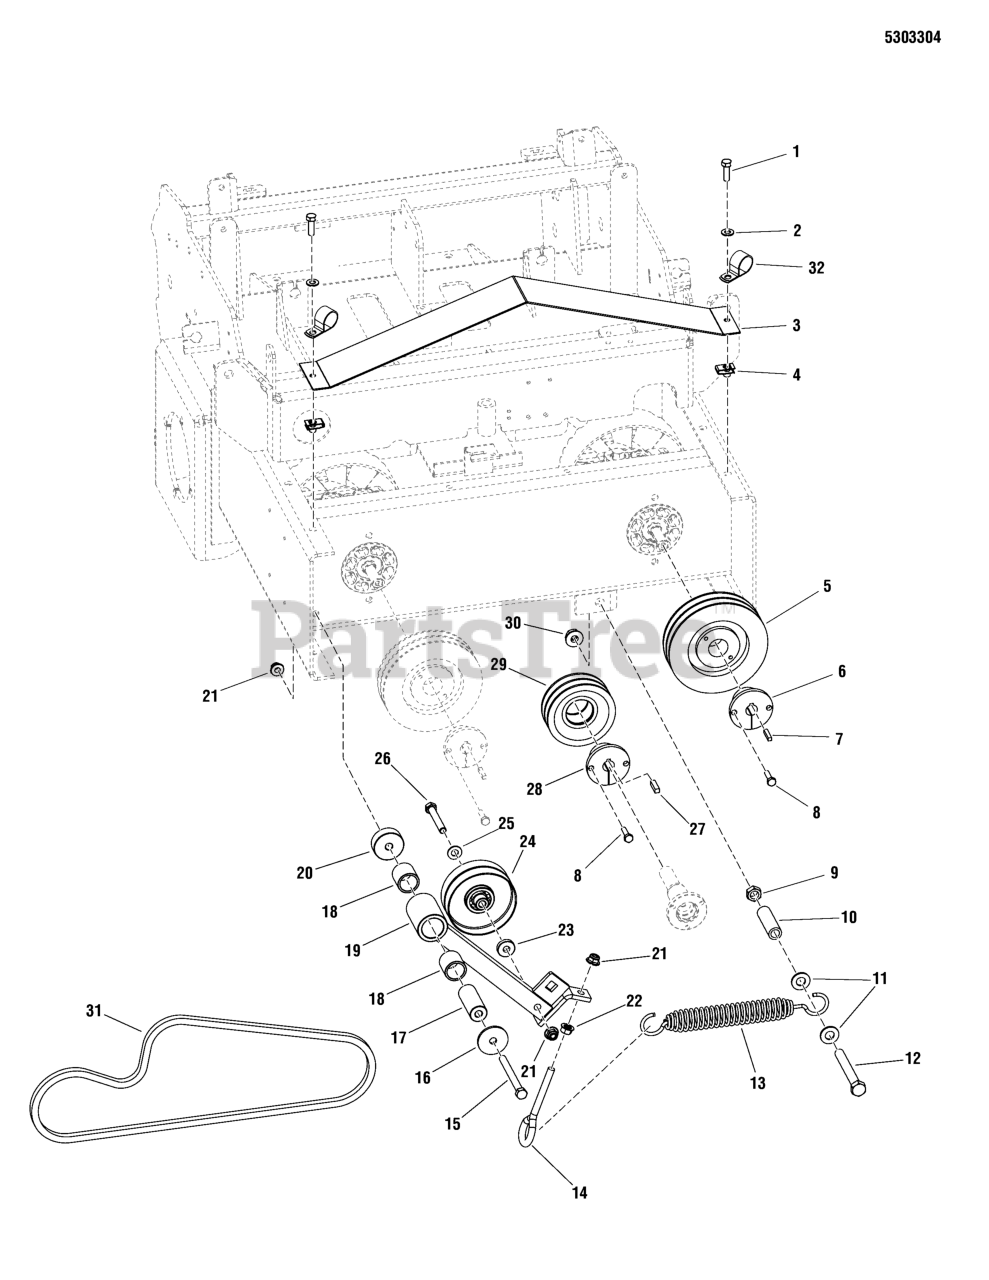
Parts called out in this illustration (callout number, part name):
1	BOLT, 5/16-18 X 1 GD5 YZ
2	WASHER, 5/16" SAE
3	GUARD, OUTFRONT BELT, PERFORATED
4	BODY CLIP, 5/16-18-7GA MATERIAL
5	PULLEY 5.00 OD, DOUBLE "A" GROOVE
6	BUSHING, 17MM, HQ
7	KEY, 5MM SQ. W/RADIUS
8	BOLT, 1/4-20 X 1" GD5 CZ
9	NUT, 1/2-13 HEX JAM
10	HOSE, 1/2" PUSH-ON 2.25"
11	WASHER, 1/2 SAE
12	BOLT, 1/2-13 X 4" GD5 CZ
13	SPRING, EXTENSION, SWIVEL, SHORT HOOK
14	EYE BOLT, 3/8-16 X 5, 2.88THRD, 1EYE, CZ
15	BOLT, 3/8-16 X 4" GD5 CZ
16	WASHER, .41 X 1.75 X .14
17	SPACER, .39 X 1.00 X 2.55, SS
18	SPACER, .39 X 1.00 X 2.55
19	WELD, ARM, PUMP DRIVE IDLER - RED
20	SPACER, .39 X 1.75 X .63, YZ
21	NUT, 3/8-16 HEX NYLOCK FLANGE
22	NUT, 3/8-16 HEX SERRATED FLANGE
23	SPACER, .39 X 1.00 X .25
24	PULLEY, FLAT IDLER 4
25	WASHER, 3/8 SAE
26	BOLT, 3/8-16 X 2-1/2" GD5 CZ
27	KEY, 1/4 SQ X 1
28	TAPER LOCK BUSHING, HQ-1-1/8"
29	PULLEY, 4.25 OD X 2 GROOVE, DH2425
30	NUT, Hex Flange, Nylock, 1/2-13
31	BELT, 55.6 EL, MATCHED SET, A-SEC
32	CLAMP, HOSE, 1.00 DIA.
